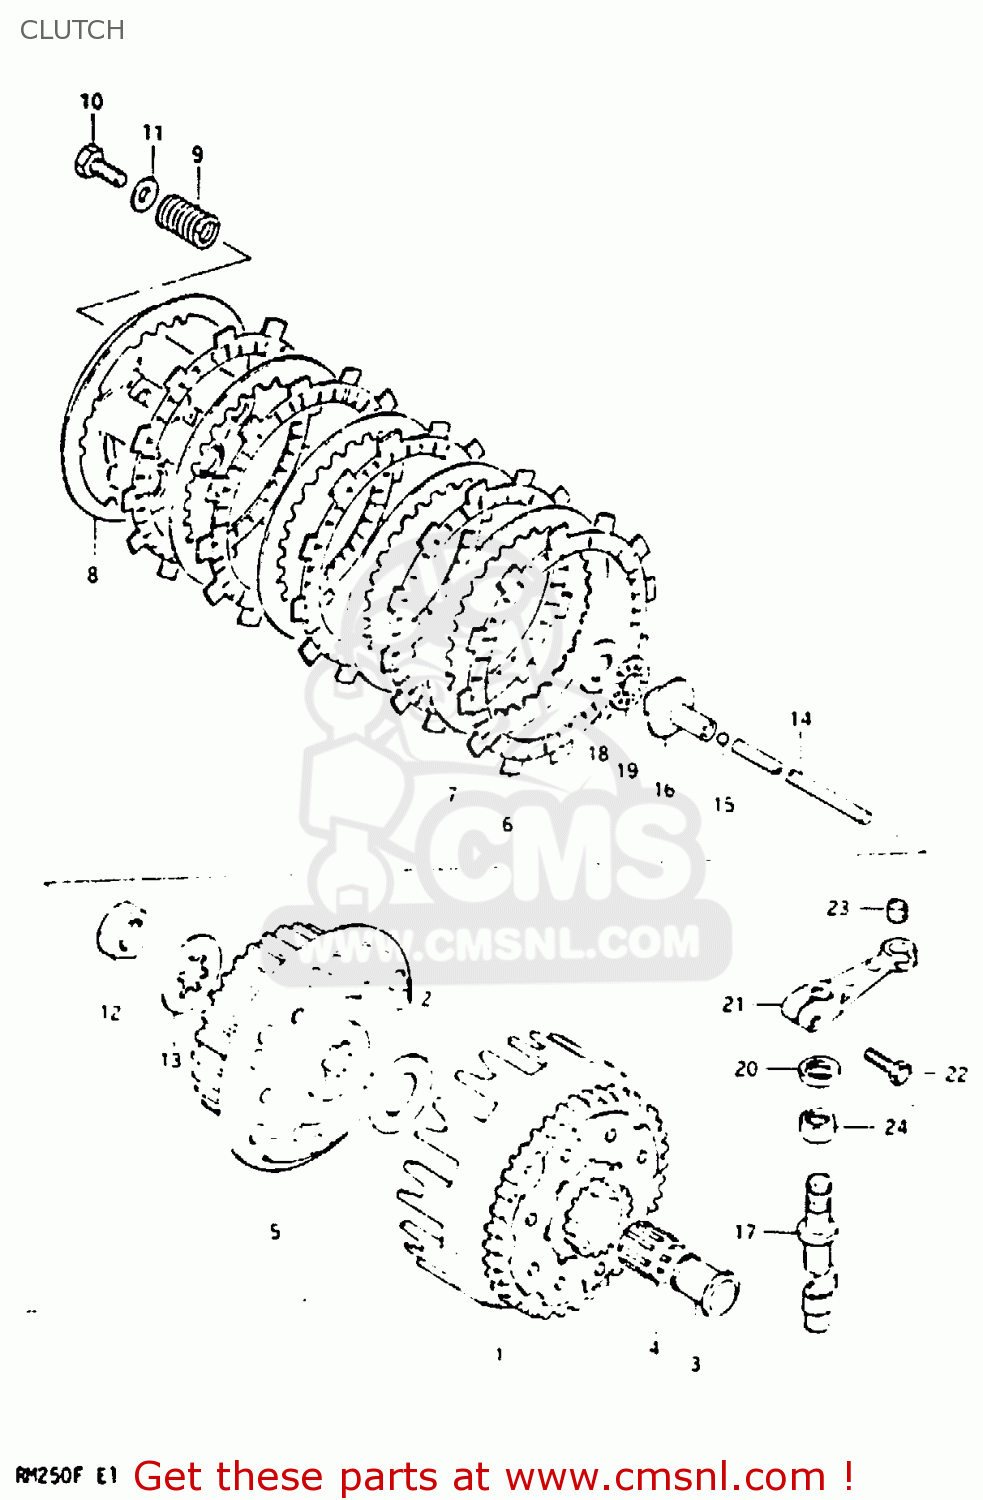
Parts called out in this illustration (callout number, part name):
1	GEAR ASSEMBLY,PRIMARY DRIVE
2	WASHER(20X38X2)
3	SPACER
4	BEARING
5	HUB,CLUTCH SLEEVE
6	PLATE,CLUTCH DRIVE (MCA)
7	PLATE,CLUTCH DRIVEN (NAS)
8	DISC,CLUTCH PRESSURE
9	SPRING
10	BOLT, UPPER
11	WASHER
12	NUT (20MM)
13	WASHER,LOCK
14	ROD,CLUTCH PUSH
15	BALL
16	PIECE,CLUTCH PUSH
17	SHAFT,CLUTCH RELEASE C
18	WASHER
19	BEARING(15X28X2)
20	SEAL,OIL(12X19X5)
21	ARM,CLUTCH RELEASE
22	BOLT
23	PIECE,RELEASE ARM END
24	BEARING(12X19X12)
